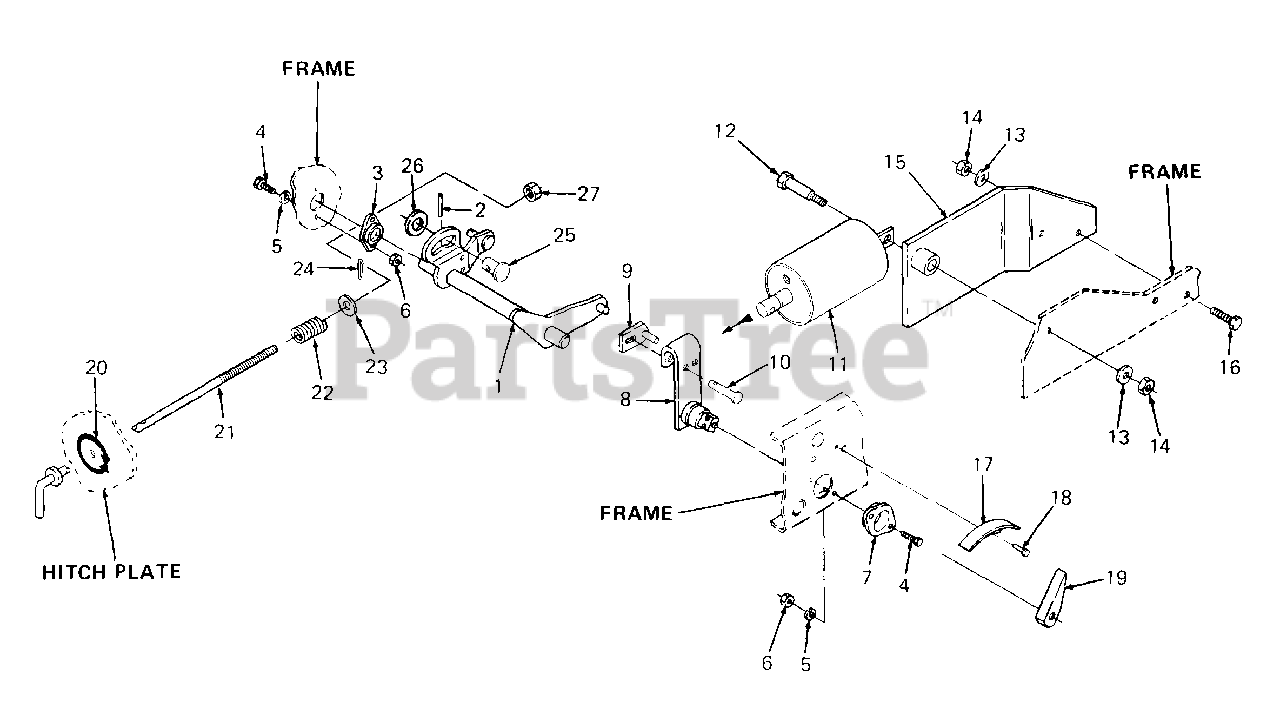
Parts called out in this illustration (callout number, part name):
3	Bushing, Lift, LH
4	Screw, Hex Cap, 1/4-20 X.75 Lg GR5
5	Washer, Lock, 1/4
6	Nut, Hex, 1/4-20 GR5
7	Bushing, Lift, RH
8	Bracket Assy, Lift
9	Pin Assy, Lift
10	Pin, Clevis, 1/2 Dia X 2.172 Lg
11	Cylinder, Hydraulic
12	Bolt, Shoulder
13	Washer, Flat, .531 X 1.06 X .134 Thk
14	Nut, Hex Center Lock, 1/2-13 GR5
15	Bracket, Cylinder
16	Screw, Hex Cap, 1/2-13 X 1.25 Lg GR5
17	Bracket, Height Indicator
18	Rivet, .156 Dia X .250 Lg
19	Indicator, Height
20	Graphic, Down Stop Adjustment
21	Rod, Down Stop Adjustment
22	Spring, Compression, .501 X .75 X 1.00 Lg
23	Washer, Flat, .656 X 1.312 X .074 Thk
24	Pin, Internal Cotter
25	Clevis, .750 X 1.00 Lg
26	Washer, Flat, .758 X 2.0 X .030 Thk
27	Nut, Hex LH Thrd, 1/4-28
